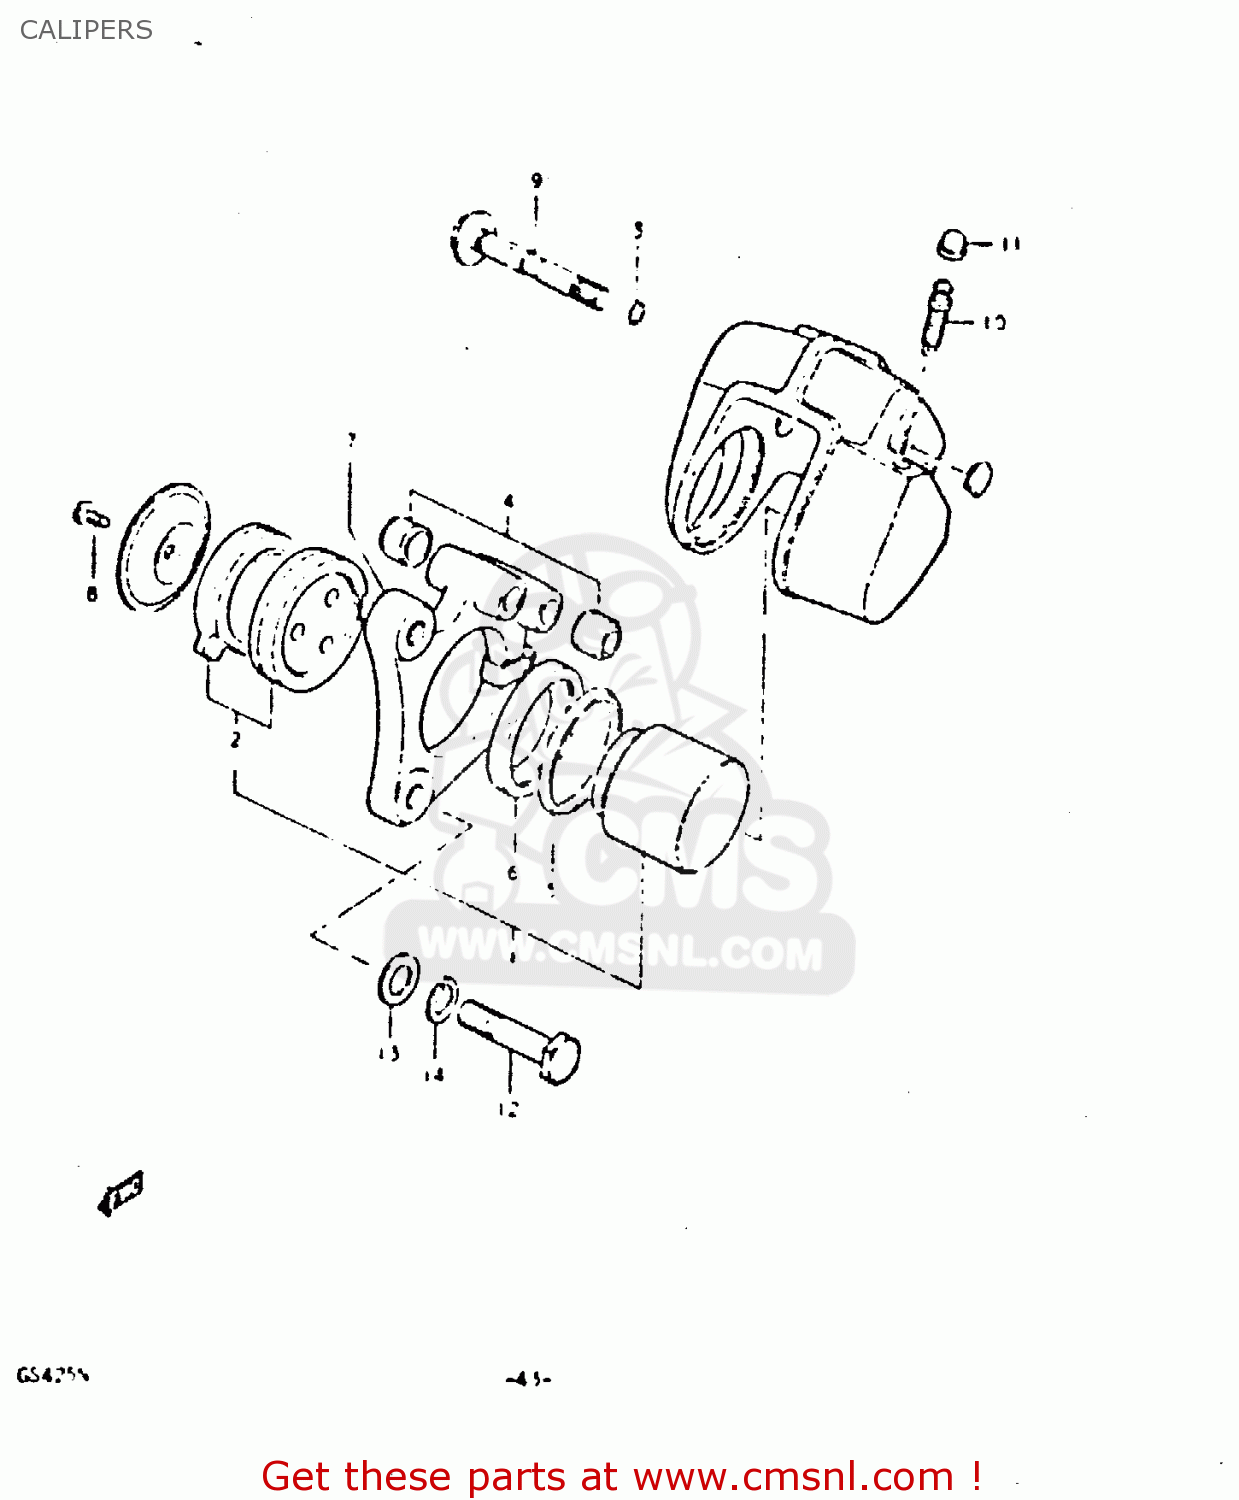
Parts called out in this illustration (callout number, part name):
1	CARRIER,CALIPER,RIGHT
2	CARRIER,CALIPER,LEFT
3	O RING
4	COVER,AXLE DUST
5	SEAL,FR CALIPE
6	BOOT,PISTON
7	HOLDER, CARIPERS LH
8	SCREW 6X12
9	AXLE,CALIPER
10	BLEEDER
11	CAP,BREATHER
12	BOLT
13	WASHER
14	LOCK WASHER
